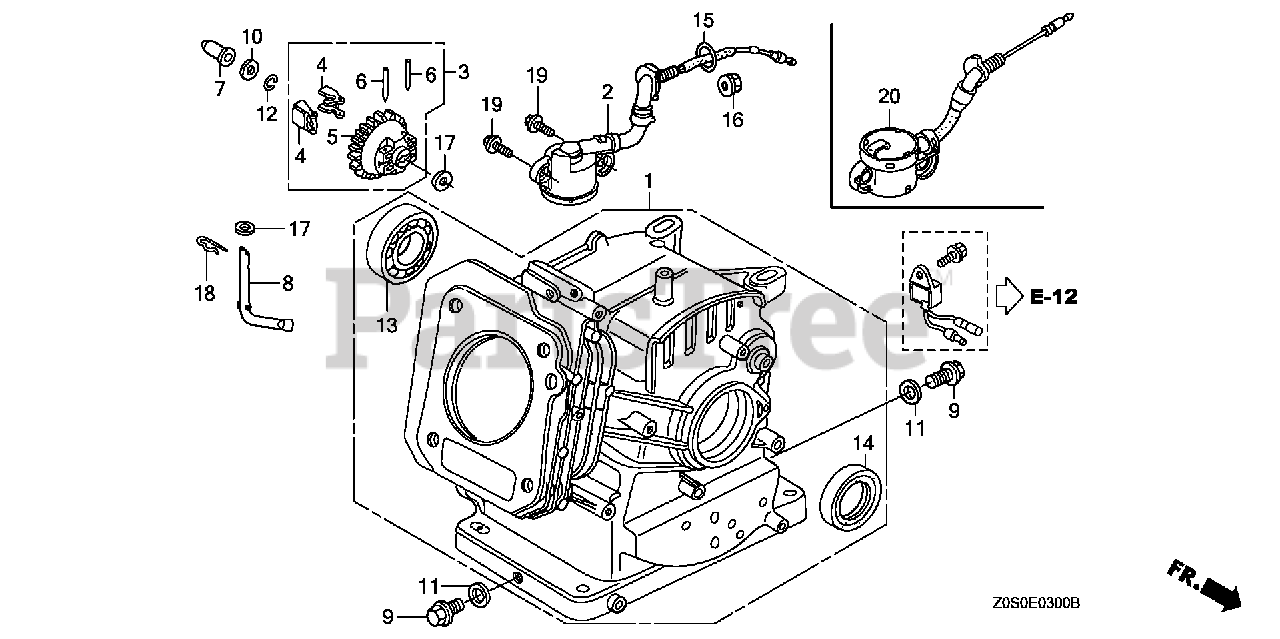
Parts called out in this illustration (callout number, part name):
1	CYLINDER ASSY. (OIL ALERT)
2	SWITCH ASSY., OIL LEVEL
3	GOVERNOR ASSY.
4	WEIGHT, GOVERNOR
5	HOLDER, GOVERNOR WEIGHT
6	PIN, GOVERNOR WEIGHT
7	SLIDER, GOVERNOR
8	SHAFT, GOVERNOR ARM
9	BOLT, DRAIN PLUG
10	WASHER, THRUST (6MM)
11	WASHER, DRAIN PLUG (10.2MM)
12	CLIP, GOVERNOR HOLDER
13	BEARING, RADIAL BALL
14	OIL SEAL (22X35X6)
15	O-RING (13.5X1.5) (ARAI)
15	O-RING (14MM) (NOK)
16	NUT, FLANGE (10MM)
17	WASHER, PLAIN (6MM)
18	PIN, LOCK (8MM)
19	BOLT, FLANGE (6X12)
